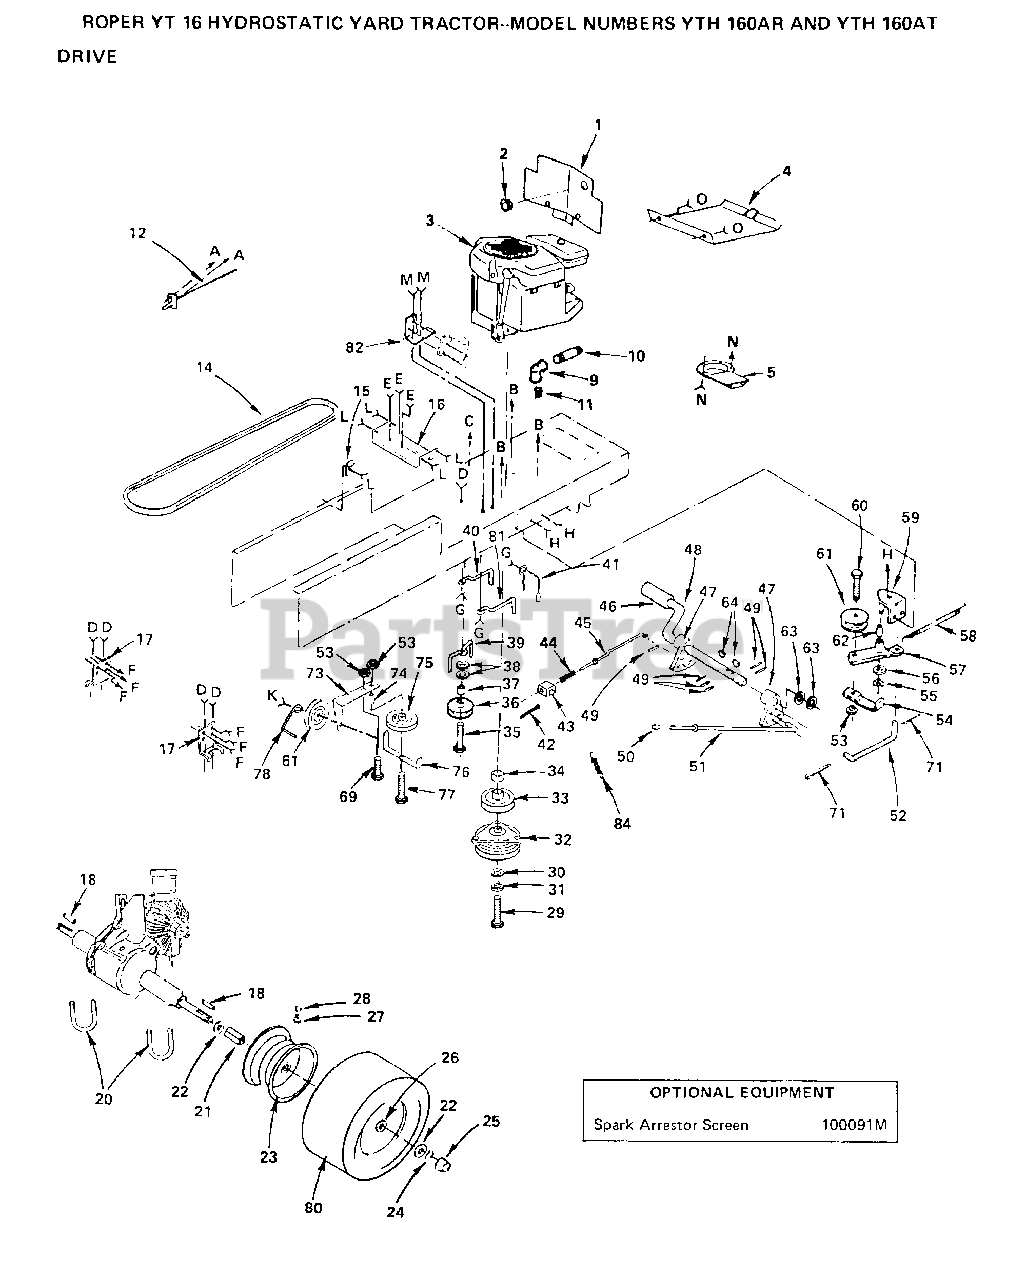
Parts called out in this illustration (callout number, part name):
2	SNAP BUSHING T
3	ENGINE, B&S
9	ELBOW
10	PIPE NIPPLE LT
11	PLUG OIL DRAIN
15	CLIP T
17	BRKT, TRANSAXLE
18	SQ KEY STD
21	SPACER HYT
22	WASHER
23	RIM REAR HYT
24	E RING HYT
25	HUB CAP
27	VALVE STEM LT
28	VALVE CAP
30	WASHER T
31	LOCKWASHER
33	PULLEY ENGINE HYT
35	BOLT
37	SPACER T
38	WASHER
42	COTTER PIN
43	TRUNION HYT
44	SPRING BRAKE HYT
46	PEDAL COVER T
47	ARM BRAKE LT
48	SHAFT, FOOT PEDAL
50	PLUNGER CAP T
52	"LINK, CLUTCH T"
55	KLIP RING
56	WASHER T
58	"SPRING, RETURN LT"
62	"LY, BEARING"
69	BOLT
71	COTTER PIN
73	BRKT IDLER HYT
74	SPACER SPLIT LTV
75	IDLER.PULLEY.LT
76	KEEPER BELT HYT
78	BELT RETAINER GT
82	BRACKET LT
84	SPRING-EXT LT
